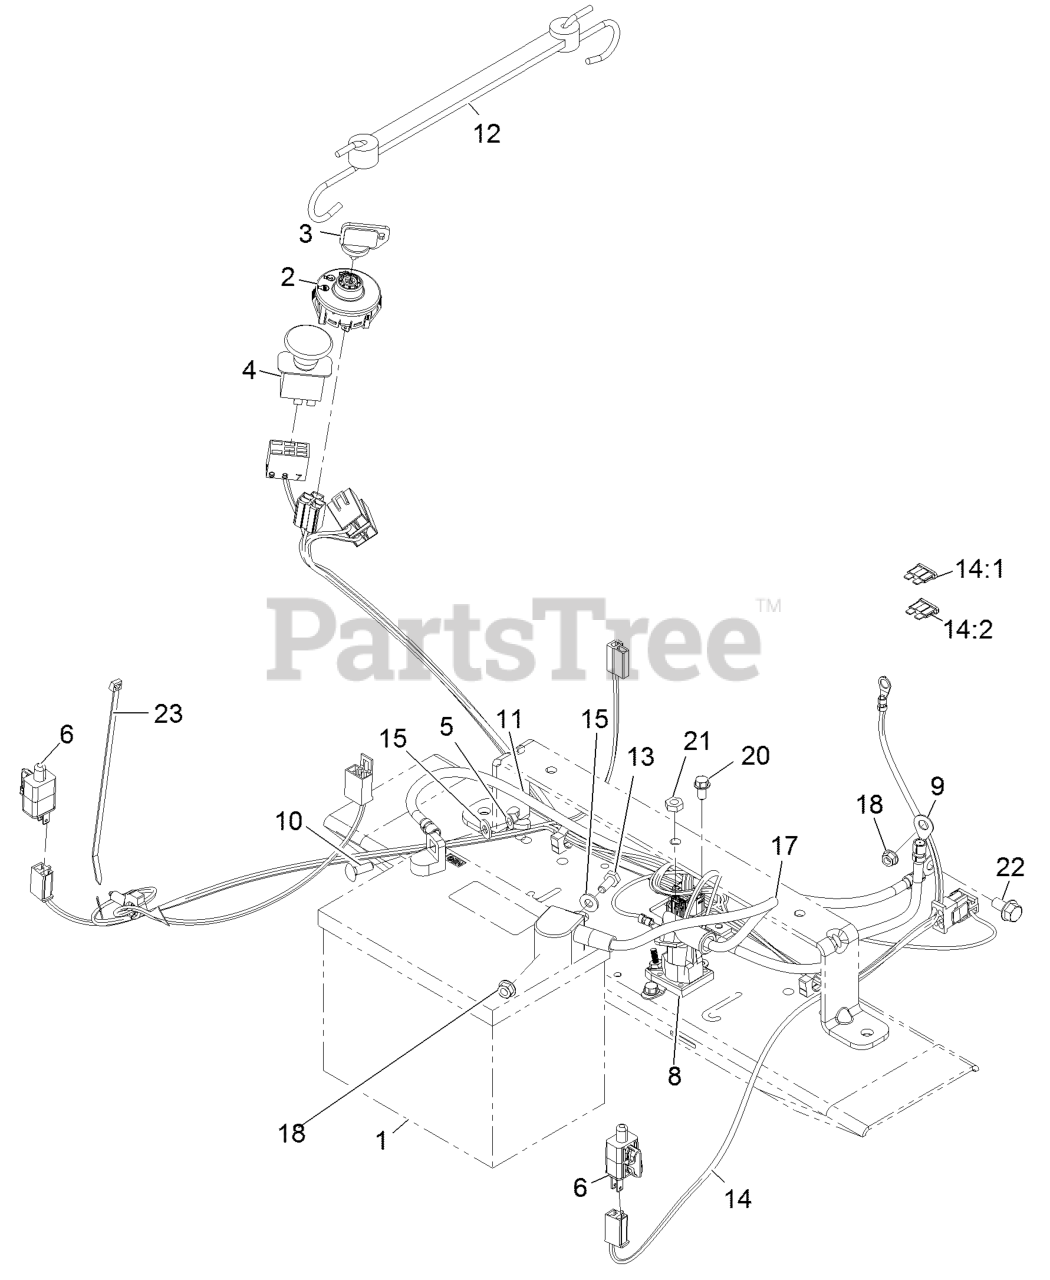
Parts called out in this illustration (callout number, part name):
1	BATTERY
3	KEY-IGNITION
4	SWITCH-PTO
5	NUT-WING
8	SOLENOID
9	CABLE-BATTERY, RED
10	BOLT-CARR
11	CABLE-BATTERY, BLACK
12	HOLDDOWN-BATTERY
13	SCREW-HH
14:1	FUSE-BLADE, 30 AMP
14:2	FUSE-BLADE, 25 AMP
15	WASHER-FLAT
17	CABLE-BATTERY, RED
20	SCREW-HWH
21	NUT-JAM
22	SCREW-HHF
23	TIE-CABLE
